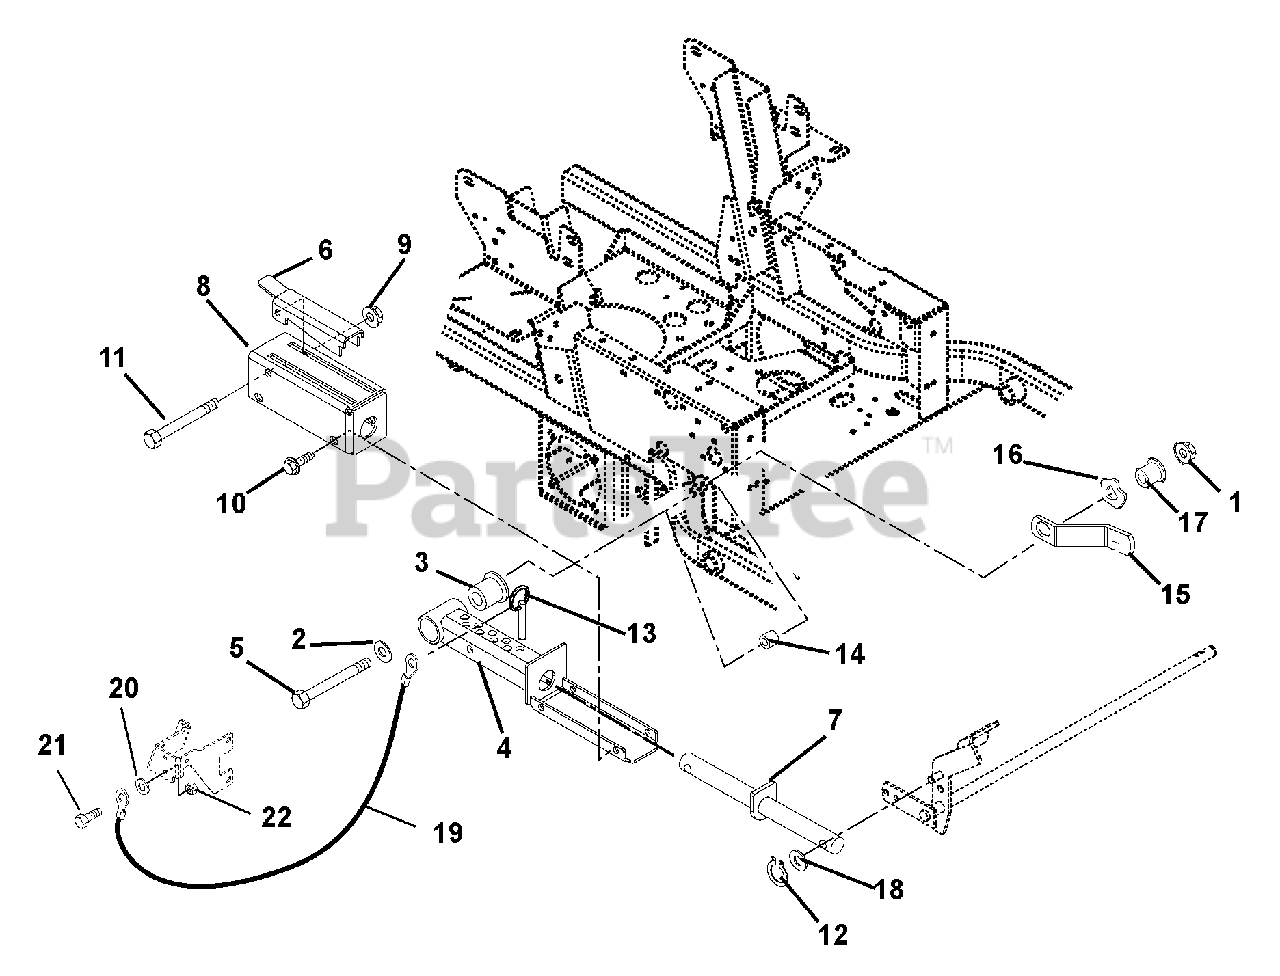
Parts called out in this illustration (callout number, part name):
1	Nut, Locking Top Flange .50-13
2	Washer, Flat Steel .531 x 1.25 x .10
3	Bearing, Pedestal Powdered Metal
4	Weldment, Mechanical Lift
5	Bolt-Hex .50-13 x 5.00 Grade 5
6	Lock-Up, Mechanical Lift
7	Weldment, Mechanical Lift Shaft
8	Weldment, Mechanical Lift Cover
9	Nut, Locking Top Flange .38-16
10	Screw, Tapping .38-16 x .50 Hex Washer Head
11	Bolt, Hex .38-16 x 3.25 Grade 5
12	Ring, Retaining External .625 x .05
13	Pin, Spring Ball .375 O.D. x 1.50
14	Spacer .516 ID x 1.00 OD x .875
16	Washer-Wave .076 x 1.120 x .080
17	Bushing-Flange .515 x .750 x .275 x 1.120
18	Washer, Flat Steel .656 x 1.31 x .095
19	Cable, Hood
20	Washer, Flat Steel .265 x .50 x .087
21	Bolt-Hex .25-20 x .75 Grade 5
22	Nut, Locking Top Flange .25-20
